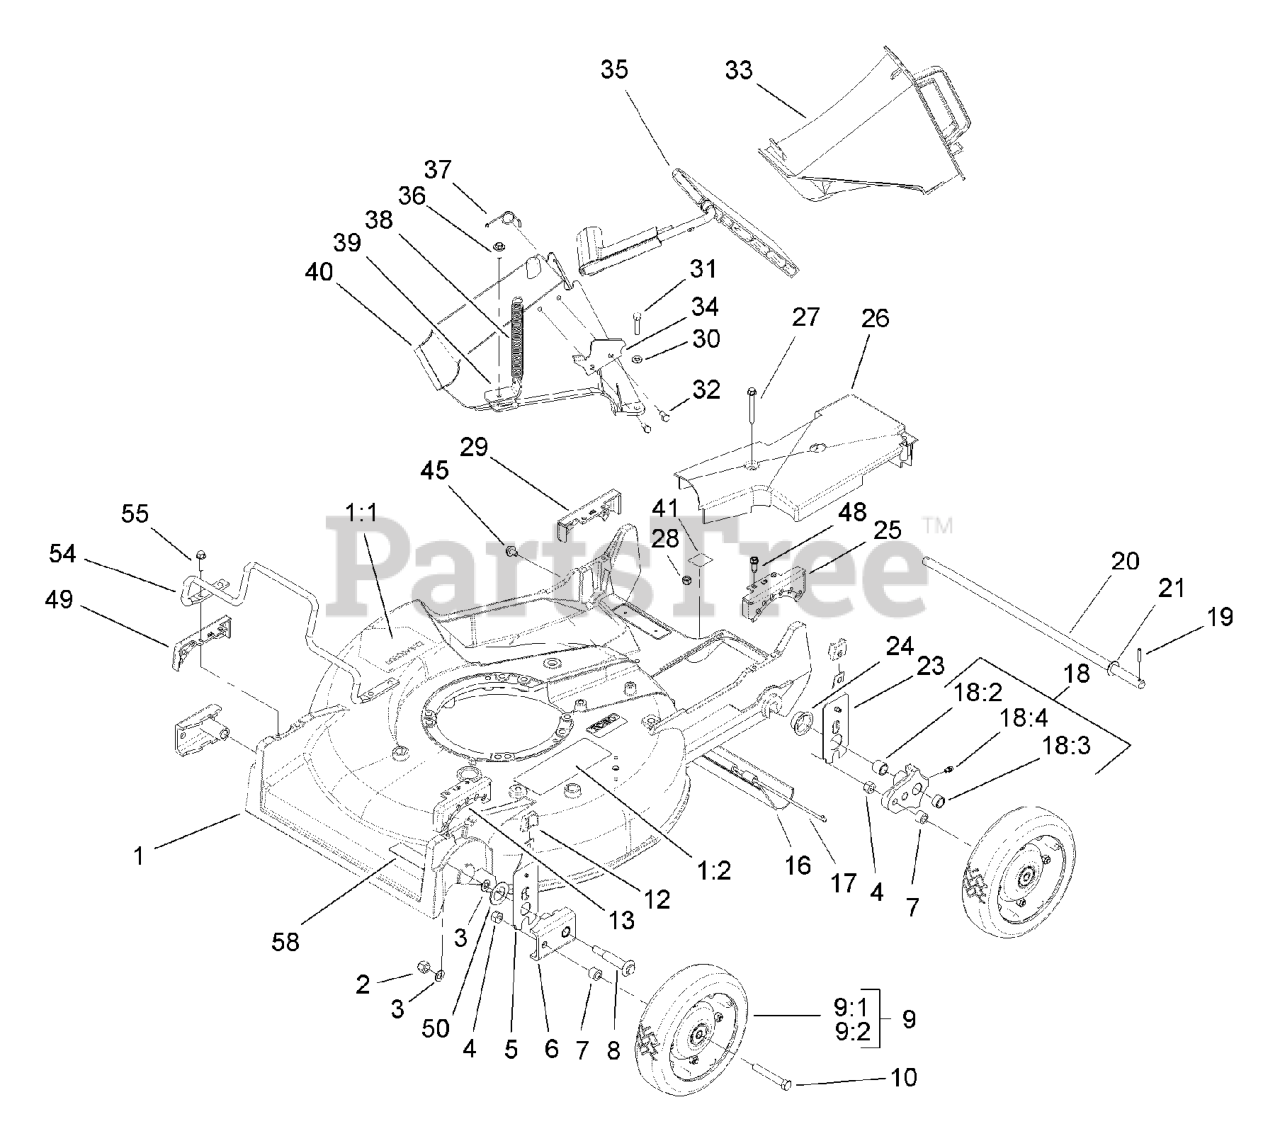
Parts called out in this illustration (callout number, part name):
1:1	DECAL-DANGER
1:2	DECAL-WARNING
2	NUT-LOCK
4	NUT-LOCK, CONE
5	FRONT SPRING ARM ASM
6	ARM-PIVOT, FRONT
7	SPACER-WHEEL
9:2	Wheel Asm
10	BOLT-CARR
12	KNOB-ARM
13	QUADRANT-FRONT, LH
17	ROD-SHIELD
18	PIVOT ARM ASM
18:2	BUSHING
18:3	BUSHING
18:4	FITTING-GREASE
19	PIN-SPIROL
20	SHAFT-AXLE, REAR
21	WASHER-PLAIN
23	REAR SPRING ARM ASM
24	CAP-END
25	QUADRANT-REAR, LH
26	COVER-BELT
27	SCREW-HWH
28	NUT-LOCK, NI
29	QUADRANT-REAR, RH
30	WASHER-FLAT
31	SCREW-HH
32	SCREW-PLASTITE
33	DISCHARGE PLUG ASM
34	LATCH-PLATE
35	DISCHARGE DOOR ASM
36	SCREW-HWH
37	RETAINER-DOOR
38	SPRING-DOOR
39	BRACKET-SPRING
40	TUNNEL-DISCHARGE
41	LABEL-GREASE, HP
45	SCREW AND WASHER ASM
48	SCREW-HWHTF
49	QUADRANT-FRONT, RH
50	WASHER-THRUST
54	GUARD-ENGINE
55	SCREW-HWHTF
58	DECAL-BLADE
